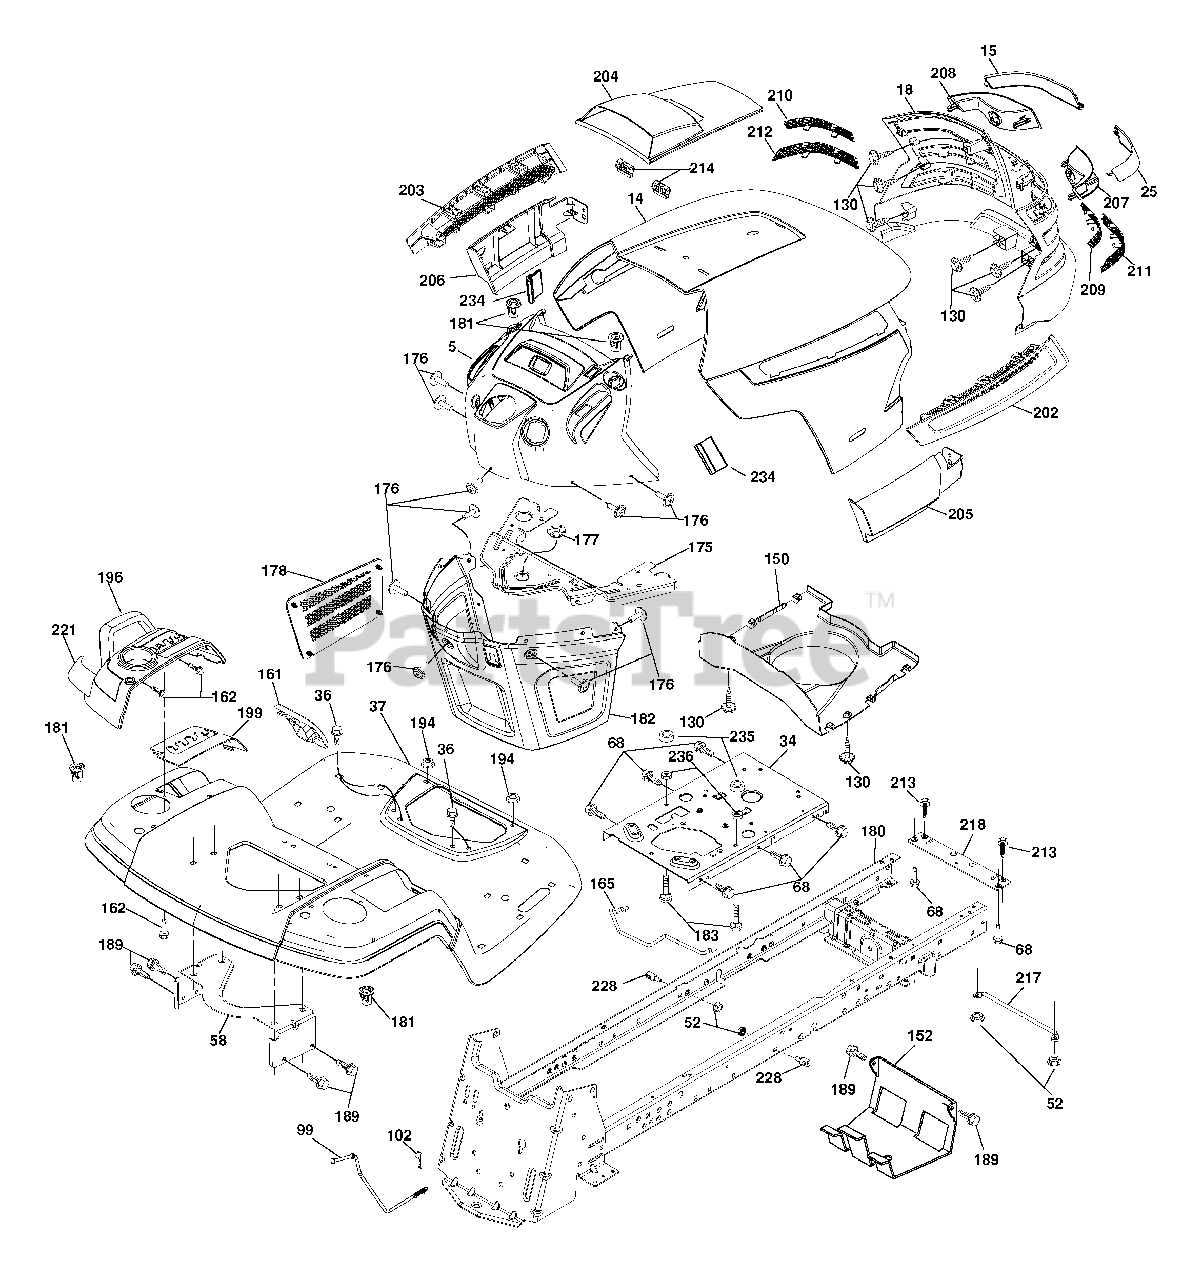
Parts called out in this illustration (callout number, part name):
14	Hood
18	Grille
34	Plate Engine
36	Screw 5/16-18 x 3/4
37	Fender
52	Nut Crown Lock 5/16-18
58	Bracket Fender
68	Screw 5/16-18 x 1/2
99	Rod Bypass Asm.
102	Retainer Spring 1
130	Screw 10 x 3/4 Single Lead Hex
150	Duct Heat Hood
152	Shield Browning/Debris
161	Console Fuel Window
162	Screw Hex Wsh Hi-Lo 1/4 x 1/2
165	Bracket Support Tank
175	Crossmember
176	Screw 10-24 x 5/8 Wshd Qdrx
177	Bushing Steering
178	Cargo Asm. Net
180	Chassis
181	Bushing Mtg. Fender Crgo.
182	Dash Lower
183	Bolt Fin Hex 5/16-18 UNC x 1-1/4
189	Screw 5/16-18 x 3/4
194	Nut Lock Hex Flange 5/16-18
196	Console Asm. Deck Lift
199	Plate Deck Lift
202	Vent Side Hood RH
203	Vent Side Hood LH
204	Vent Asm Hood Top
205	Skirt Hood Side RH
206	Skirt Hood Side LH
209	Insert Hex Top RH
210	Insert Hex Top LH
211	Insert Hex Bottom RH
212	Insert Hex Bottom LH
213	Bolt Hex Hd 5/16-18 unc x 3/4
214	Clip Retainer
216	Screw 5/16-18 x 1/2
217	Rod Pivot
219	Stud Fastener
220	Nut Lock Hex Flange
221	Reflector LH
228	Stud Fastener
234	Bumper Hood
235	Spacer Fender
236	Nut Center Lock 5/16-18 UNC
